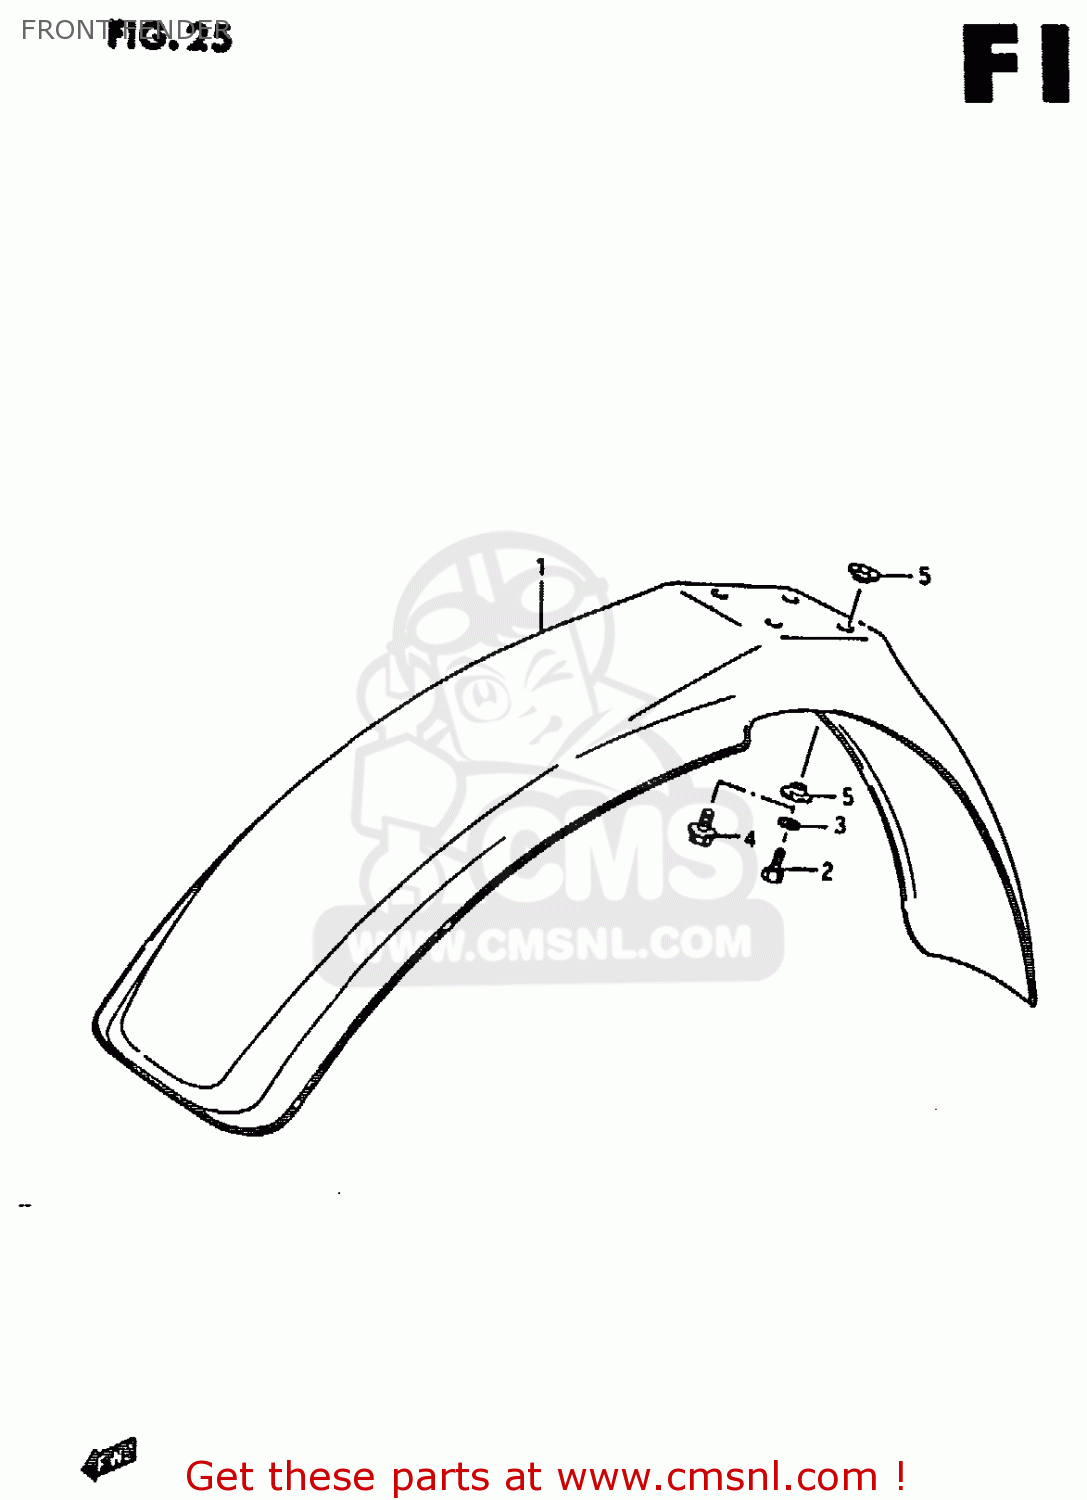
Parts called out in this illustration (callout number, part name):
1	FENDER,FRONT
2	BOLT
3	WASHER,LOCK
4	BOLT
5	WASHER
